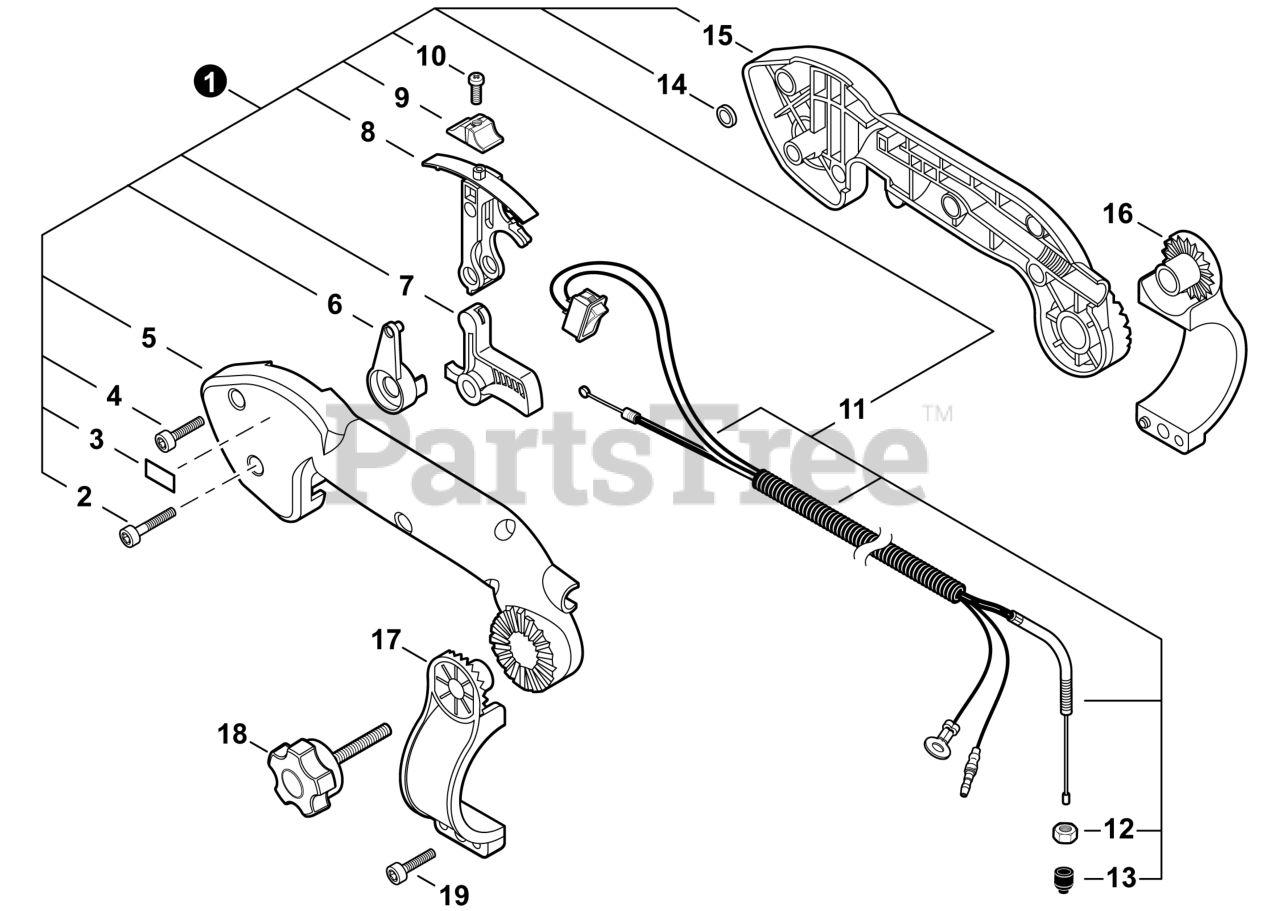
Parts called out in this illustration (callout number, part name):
1	THROTTLE CONTROL KIT - TUBE MOUNT
2	BOLT, TORX 5×25
3	LABEL - CAUTION - IDLE
4	BOLT, TORX 5×20
5	CONTROL HANDLE - LEFT
6	LEVER, THROTTLE
7	TRIGGER, THROTTLE
8	CONTROL, THROTTLE
9	KNOB, CONTROL
10	SCREW 3×14
11	CABLE ASSY, CONTROL
12	NUT, HEX M6
13	CAP, DUST
14	WASHER 5.2×8×0.5
15	CONTROL HANDLE - RIGHT
16	BRACKET, RIGHT
17	BRACKET, LEFT
18	KNOB, SCREW
19	BOLT, TORX 5×20
